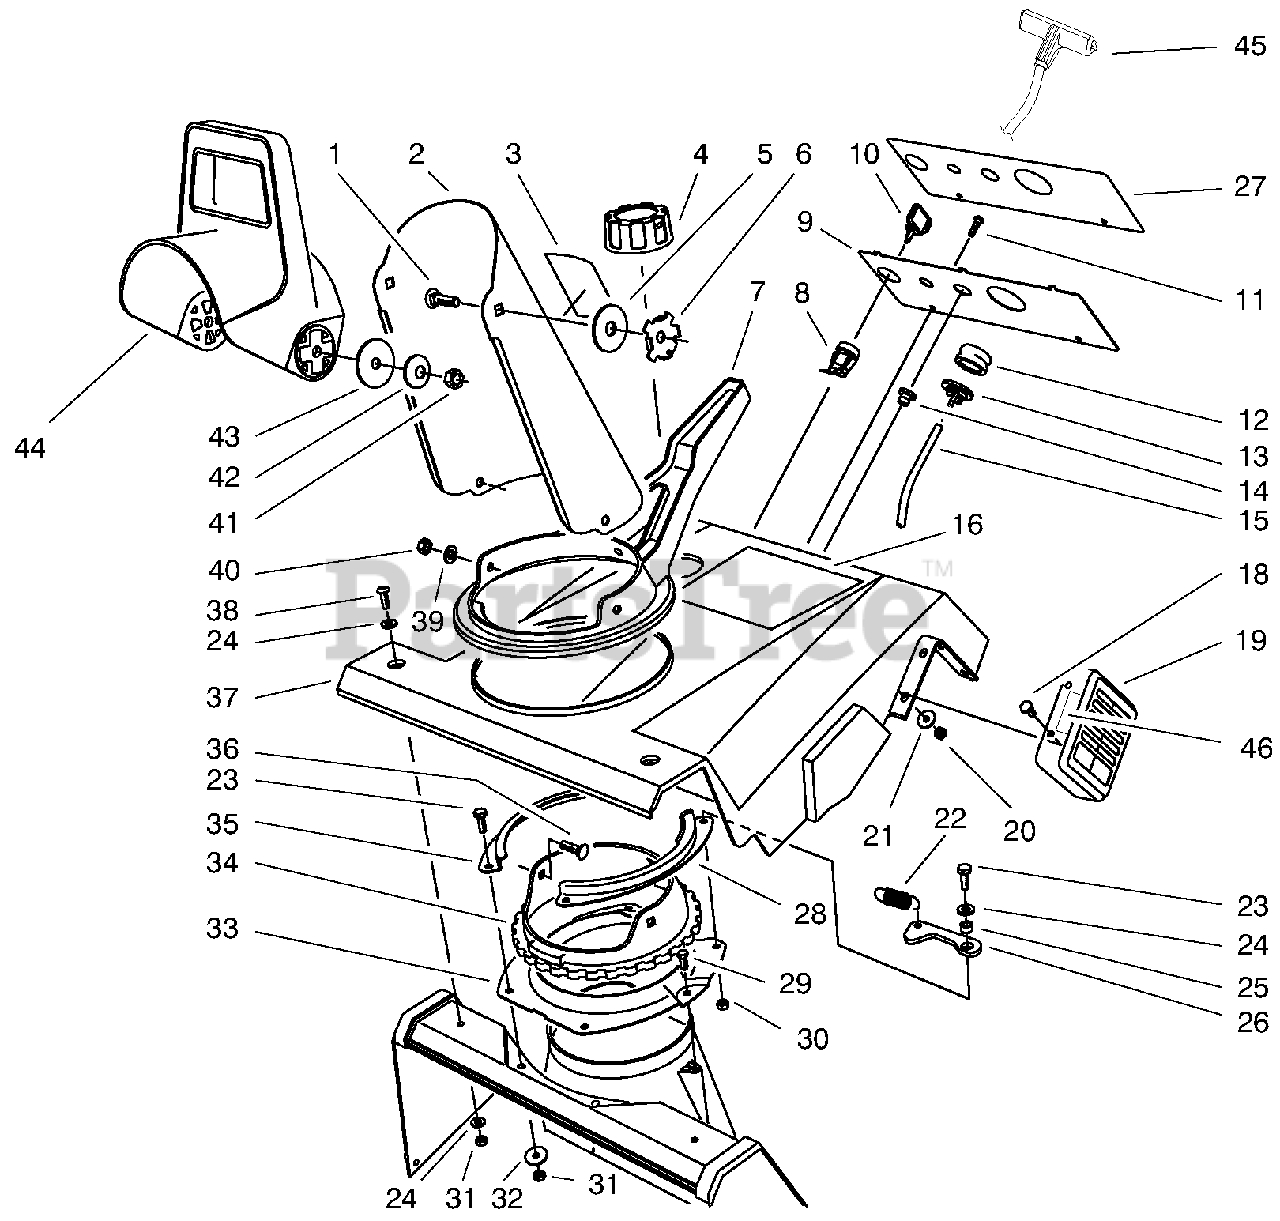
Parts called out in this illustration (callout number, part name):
1	Bolt-Carriage
2	Discharge Chute Assembly (Incl. Ref. #3)
3	Decal-Danger
4	Gas Cap Assembly
5	Washer-Rubber
6	Plate-Friction
7	Handle-Chute
8	Switch-On-Off
9	Panel-Control (Model No. 28220)
10	Key-Ignition
11	Screw-Slotted Flange Hd.
12	Bulb-Primer
13	Body-Primer
14	Guide-Rope
15	Hose-Primer
16	Decal-320 (Model No. 28220)
18	Screw-Hex. Hd.
19	Guard-Muffler
20	Nut-Lock
21	Washer-Flat
22	Spring-Extension
23	Screw-Hex. Hd.
24	Washer-Flat
25	Spacer-Detent Arm
26	Arm-Detent
27	Decal-Control Panel (Model No. 28220)
28	Retainer-Chute Ring L.H.
29	Screw-Hex. Flange Hd.
30	Nut-Lock
31	Nut-Lock
32	Washer-Flat
33	Support-Chute Ring
34	Ring-Chute
35	Retainer-Chute Ring R.H.
36	Bolt-Carriage
37	Shroud-Upper
38	Screw-Pan Hd.
39	Washer-Flat
40	Nut-Keps
41	Nut-Lock
42	Washer-Belleville
43	Washer-Flat
44	Deflector-Discharge
45	Handle-Starter
46	Decal-Hot
